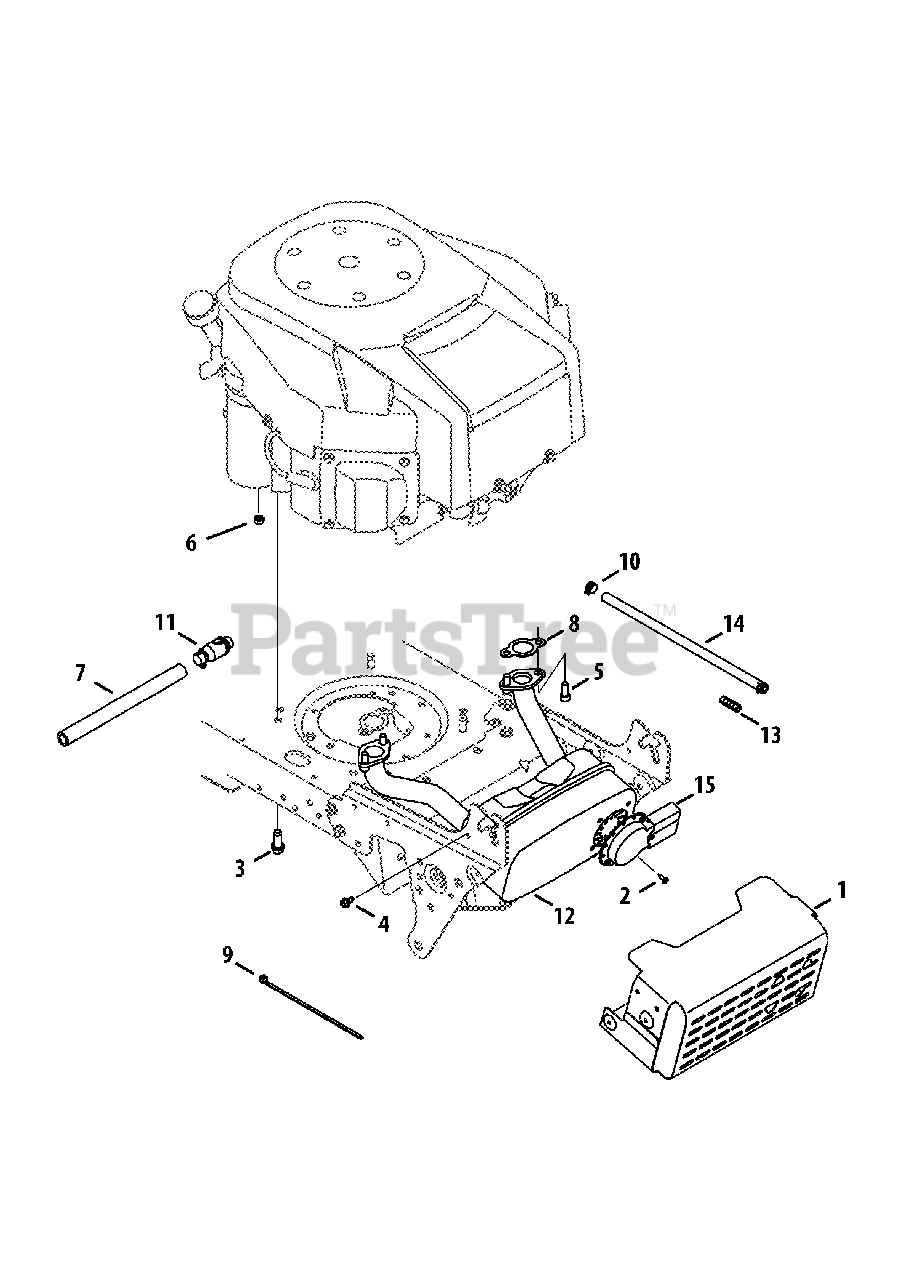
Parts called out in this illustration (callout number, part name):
1	Shield Ass’y, Muffler
2	Screw, Ab, #8-18, 0.500,
3	Screw, Self-tapping, 3/8-16, 1.000,
4	Screw, Self-tapping, 1/4-20, 0.500,
5	Screw, Socket Head, 5/16-18, .750
6	Nut, Sems, 1/4-20
7	Hose, Extension, Oil Drain
8	Gasket, Exhaust, Briggs
9	Cable, Tie, 3/16 x .05 x 7.4
10	Clamp, Hose, .490 Dia.
12	Muffler, Briggs Twin
14	Hose, Fuel, Low Permeation, 1/4
15	Deflector, Muffler, Long
